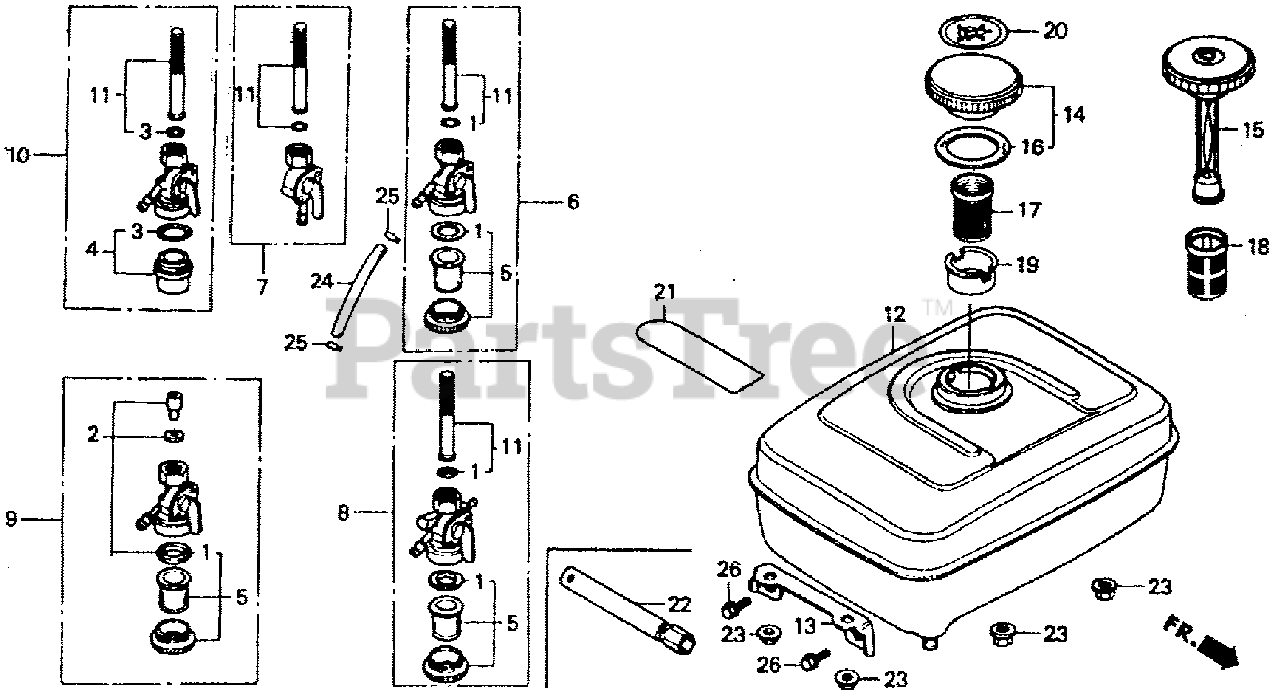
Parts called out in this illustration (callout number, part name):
1	GASKET SET, VALVE
2	GASKET SET, VALVE (NOT AVAILABLE)
3	GASKET SET, PETCOCK (CONTAINS 1 LARGE & 1 SMALL. USE AS NEEDED)
4	CUP, FUEL STRAINER
5	CUP SET, FUEL STRAINER
6	PETCOCK ASSY.
7	PETCOCK ASSY.
8	PETCOCK ASSY.
9	PETCOCK ASSY.
10	PETCOCK ASSY.
11	SCREEN SET
12	TANK, FUEL *NH31* (MCKINLEY WHITE)
13	STAY, FUEL TANK
14	CAP, FUEL FILLER
15	GAUGE, FUEL (ENGLISH)
16	GASKET, FUEL FILLER CAP
17	FILTER, FUEL
18	FILTER, FUEL
19	HOLDER, FUEL FILTER
20	MARK, CAUTION (EXTERNAL)
21	MARK, CAUTION (ENGLISH/FRENCH)(SPANISH)
22	WRENCH, SPARK PLUG
23	NUT, FLANGE (8MM)
24	BULK HOSE, FUEL (4.5X3000) (4.5X85)
25	CLIP, TUBE (B8)
26	BOLT, FLANGE (8X16)
